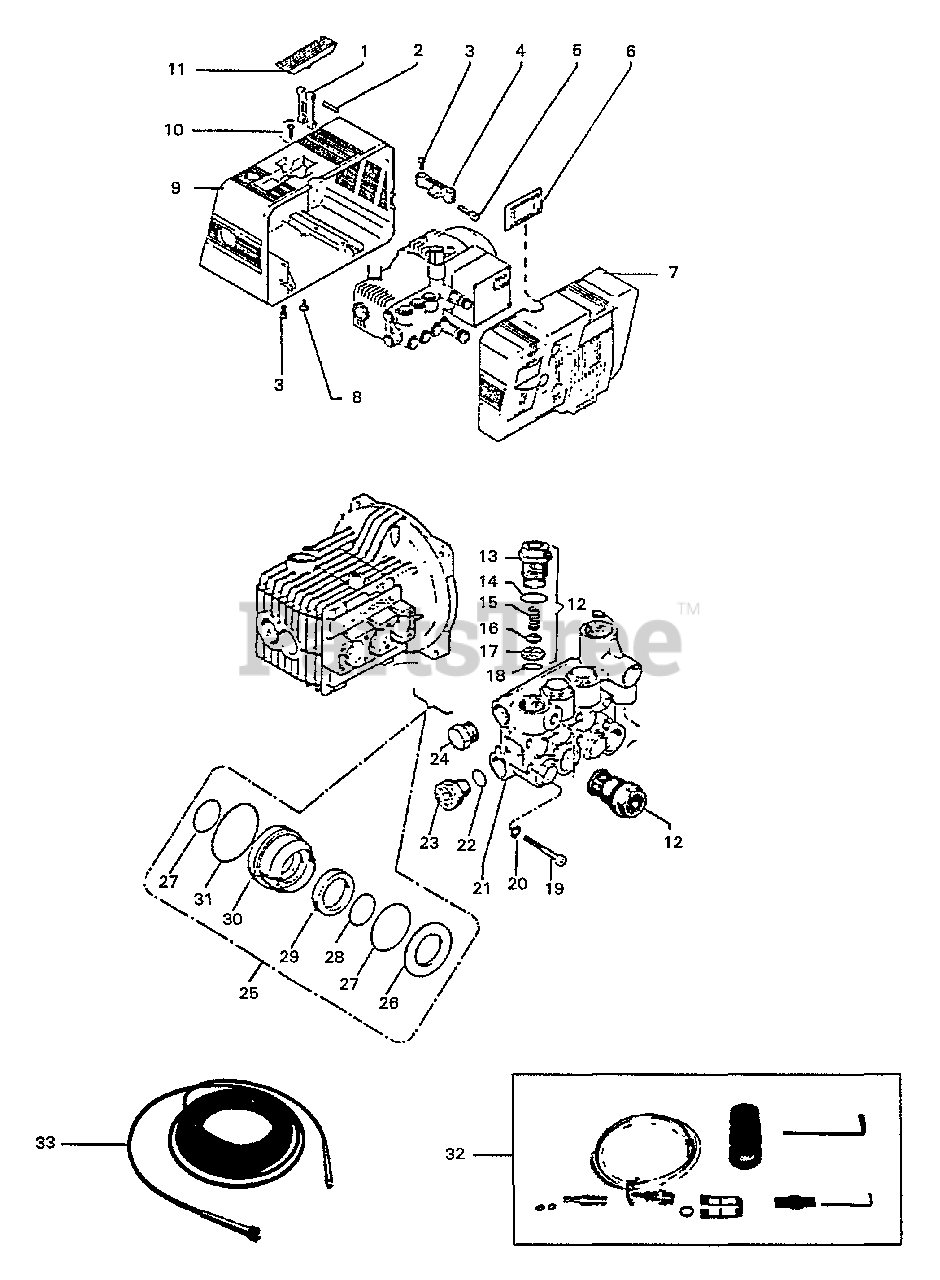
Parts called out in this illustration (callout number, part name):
1	ARM, HANDLE
2	PIN - 8.5X34
3	SCREW - 8X16
4	PLATE, HANDLE RETAINER
5	PIN, HANDLE RETAINER
6	PLATE, ON-OFF
7	COVER - FRONT
8	PLUG
9	COVER - REAR
10	SCREW - 4X13
11	HANDLE
12	VALVE KIT
13	CAP, VALVE
14	O-RING
15	SPRING, VALVE
16	PLATE
17	SEAT, VALVE
19	SCREW - 6X40
20	LOCKWASHER - 6
21	MANIFOLD
22	O-RING
23	PLUG
24	CAP, OIL DRAIN PLUG
25	RETAINER REBUILD PACKING KIT
26	WASHER
27	O-RING
28	O-RING
29	PACKING
30	PACKING, RETAINER
31	O-RING
32	ACCESSORY KIT
33	HOSE - 8M
